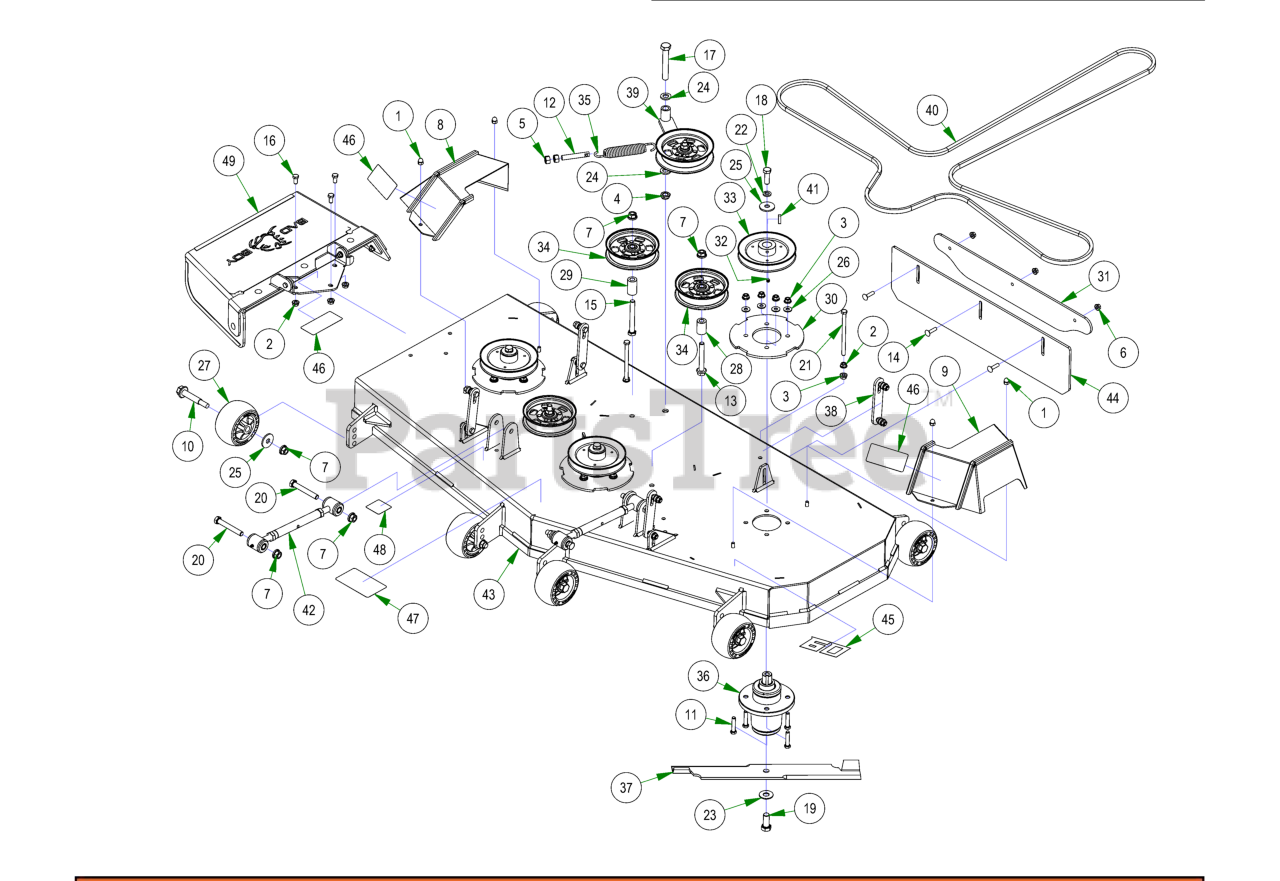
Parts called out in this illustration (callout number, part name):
1	5/16-18 ACORN NUT HIGH-CROWN ZC
2	3/8-16 HEX SERRATED FLANGE NUT HARD/ZINC
3	3/8-16 NYLON INSERT FLANGE LOCKNUT (GR.F) ZINC
4	5/8-11 NYLON INSERT JAM LOCKNUT ZINC
5	1/2-13 HEX NUT ZINC
6	5/16-18 NYLON INSERT FLANGE LOCKNUT ZINC
7	1/2-13 NYLON INSERT FLANGE LOCKNUT ZINC
8	2021 Maverick 54”/60” RH Pulley Cover
9	2021 Maverick 54”/60” LH Pulley Cover
10	Deck Wheel Bolt
11	3/8-16 X 1-3/4 HEX C/S (GR.5) ZC
12	All Thread
13	1/2-13 X 3-1/2 HEX FLANGE BOLT (GR.8) ZINC
14	5/16-18 X 1-1/4 CARRIAGE BOLT ZINC
15	1/2-13 X 4 HEX CAP SCREW (GR.8) ZINC YELLOW
16	3/8-16 X 3/4 HEX CAP SCREW (GR.5) ZINC
17	5/8-11 X 4 HEX CAP SCREW (GR.8) ZINC YELLOW
18	1/2-20 X 1-1/2 HEX CAP SCREW (GR.5) ZINC
19	5/8-18 X 1-1/2 HEX CAP SCREW (GR.8) ZINC YELLOW
20	1/2-13 X 3-1/2 HEX CAP SCREW (GR.5) ZINC
21	3/8-16 X 5-1/2 HEX CAP SCREW (GR.5) ZINC
22	1/2 SPLIT LOCKWASHER (GR.8) ZINC/YELLOW
23	5/8 USS FLAT WASHER (1-3/4" OD) GR.8 ZINC YELLOW
24	.635 ID X 1.120 OD X .140 THICK FLAT WASHER NYLON
25	1/2 BELLEVILLE WASHER (1-5/8 OD X .140 THK) ZINC
26	5/16 USS FLAT WASHER (7/8 OD) ZINC
27	Deck Wheel
28	.502 ID X .750 OD X 1.500 Long Spacer
29	1 3/4" Pulley Spacer
30	Deck Spindle Support Plate
31	2023 4" & 5" Stripping Kit Plate
32	5/16-24 X 1/4 SOCKET SET SCREW (CUP PT) PLAIN
33	6 1/4" Drive Pulley
34	5-3/4 Idler Pulley
35	Deck Idler Spring
36	OUTLAW SPINDLE ASSEMBLY
37	60" High Lift Fusion Blade
38	Deck Hanger Assembly
39	2017 MZ/ZT Deck Idler Assembly
41	1/4 X 1 SQ MACHINERY KEY 1018 STL PLN
42	2018 Maverick Turnbuckle (Top Link)
43	2023 60" x 5" Deck
44	2023 ZT Stripping Kit Rubber
45	60" Deck Decal
46	Danger Decal-Spindle/Discharge
47	Deck Belt Route Decal
48	Deck Impact Patent Decal 9591803
49	Discharge Chute Assembly
